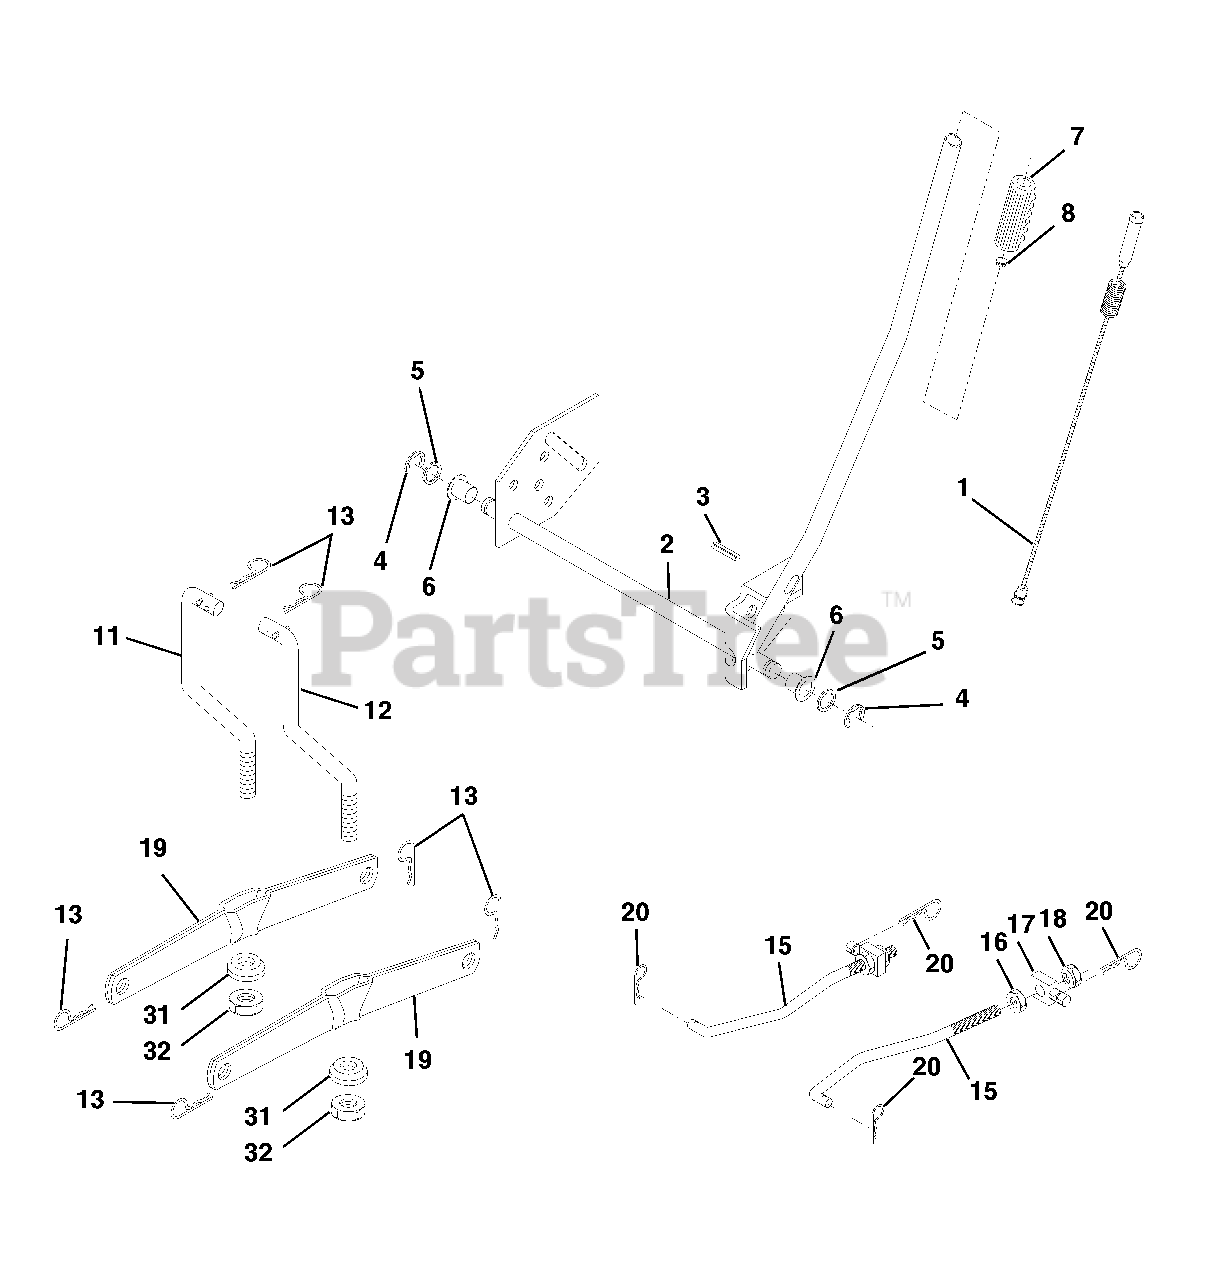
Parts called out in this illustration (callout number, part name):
1	Wire Asm Inner W/plunger LT
2	Shaft Asm Lift
3	Pin Groove
4	E-Ring #5133-62
5	Washer PLTD 21/32 X 1 X 21 ga
6	Bearing Nylon Blk 629 Id
7	Grip Handle Bicycle
8	Button Plunger Black
11	Link Lift LH
12	Link Lift RH
13	Retainer Spring
15	Link Front
16	Nut Jam Hex 1/2-13 Unc
17	Trunnion Blk Zinc
18	Nut Lock W/wsh 1/2-13unc
19	Arm Suspension Rear
20	Spring, Retainer
31	Bearing Pvt. Lift Spherical
32	Nut Crownlock 3/8-24
